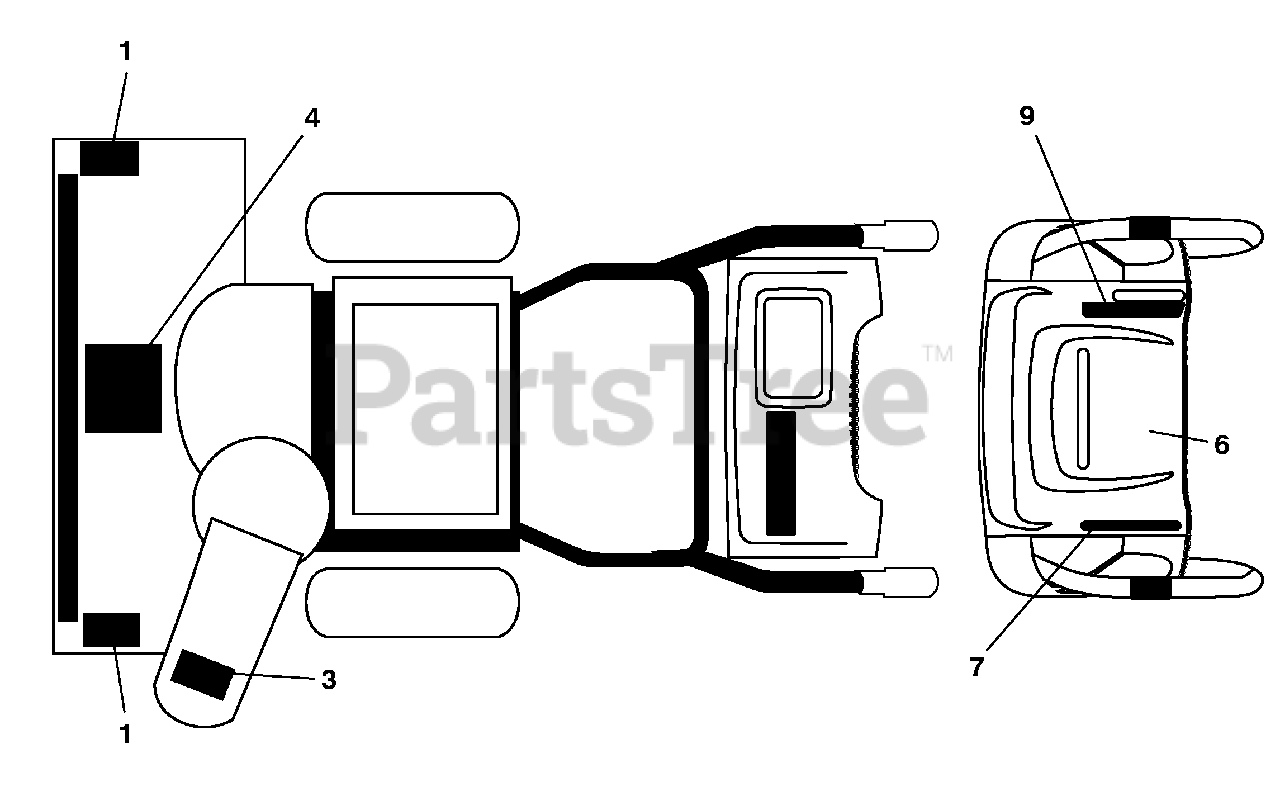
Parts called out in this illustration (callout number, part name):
1	DECAL, DANGER
3	DECAL, DANGER, DEFLECTOR
4	DECAL, DANGER
6	DECAL, INSTRUCTION
7	DECAL, LT. WO/DEFL. GRY
9	DECAL, RT. SPD/LEV/PWRST/GRY
